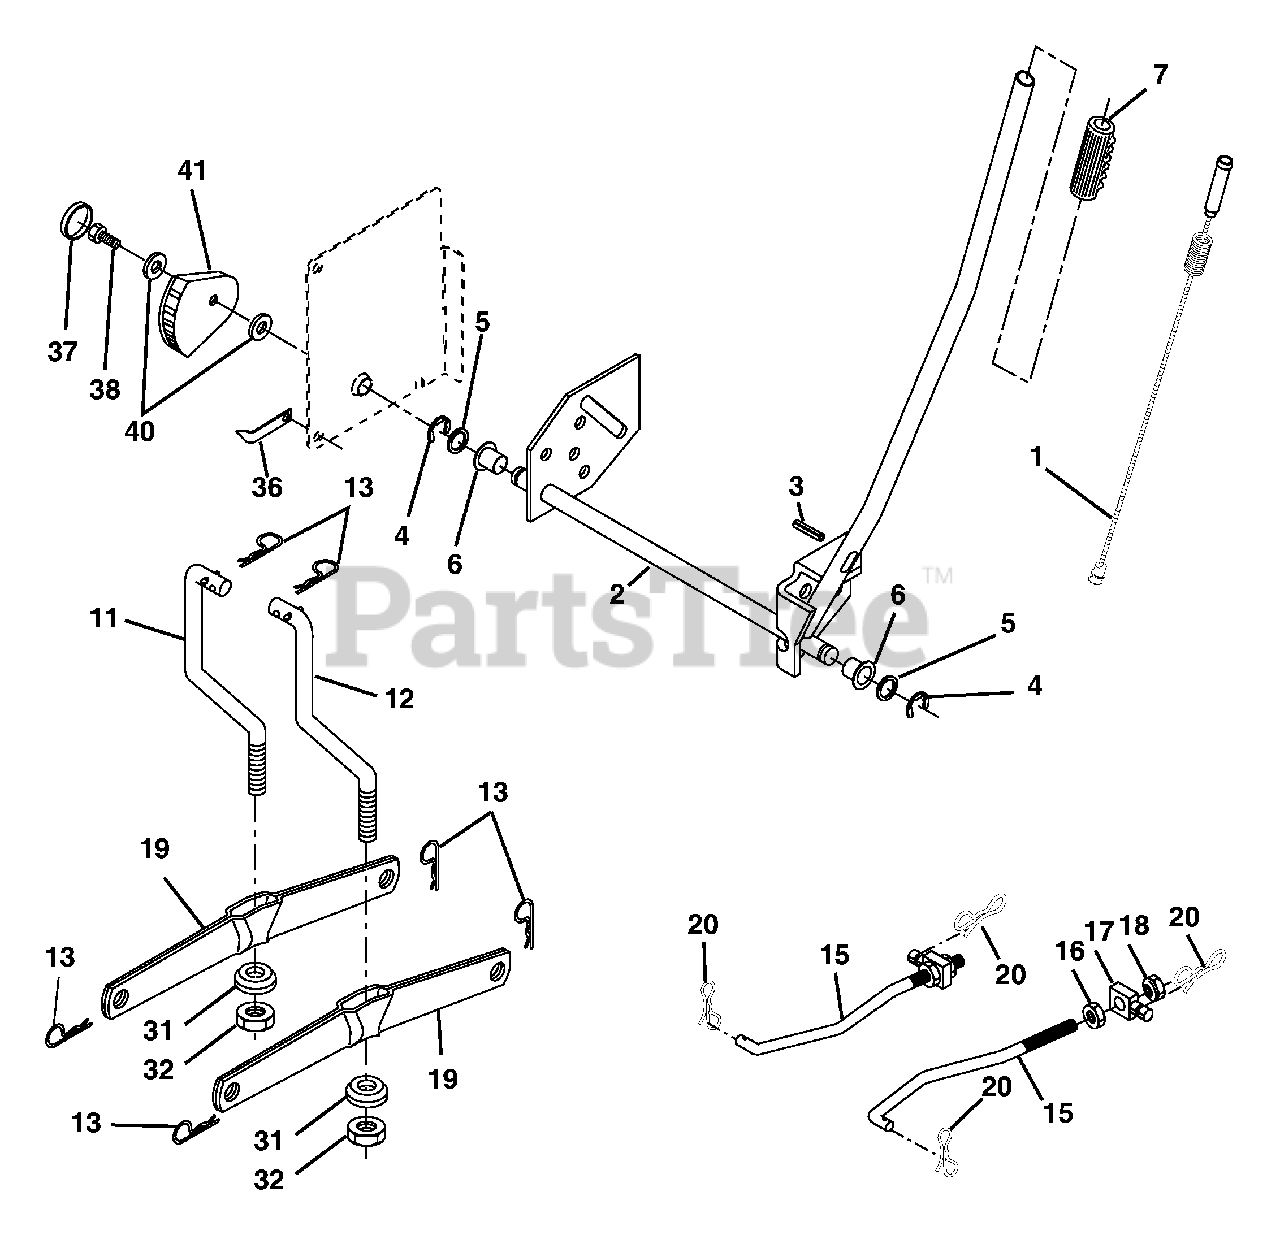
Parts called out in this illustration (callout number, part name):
1	Plunger Asm.
2	Shaft Asm Lift RH w/Inf
3	Pin Groove 2"
4	E Ring #5133-62
5	Washer 21/32 x 1 x 21 Ga.
6	Bearing Nylon Blk 629 Id
7	Grip Handle
11	Link Lift LH Fixed Length
12	Link Lift RH Fixed Length
13	Retainer Spring
15	Link Front
16	Nut Jam Hex 1/2-13 unc
17	Trunnion
18	Nut Lock W/Wsh 1/2-13 unc
19	Arm Suspension Rear
20	Pin Cotter 7/16 Bow Tie Lock
31	Bearing Pvt Lift
32	Nut Crownlock 3/8 - 24
36	Pointer Height Indicator
37	Plug Hole Blk 1.485/1.515 Dia.
38	Screw 5/16-18 x 1
40	Washer 11/32 x 1-1/2 10 Ga.
41	Indicator Height STLT
